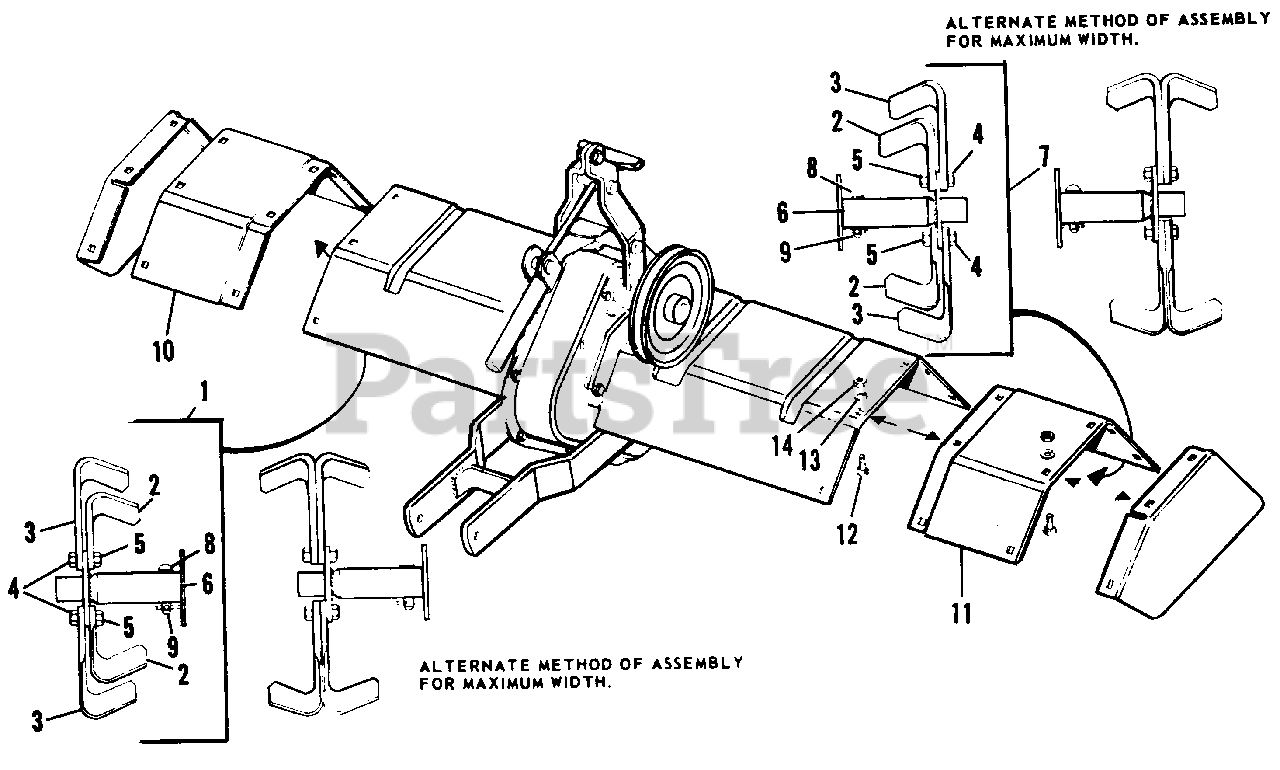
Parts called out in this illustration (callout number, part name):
1	Blade Assembly, L.H.
2	Blade, L.H. Tine
3	Blade, R.H. Tine
4	Hex. Capscrew, 7/16"-20 x 1-1/4"
5	Full Lock Nut,7/16"-20
6	Plate Assy. Tine Extension
7	Blade Assembly, R.H.
8	Tine Shaft Pin
9	Spring Clip
10	Deflector Extension, R.H.
11	Deflector Extension, L.H.
12	Carriage Bolt, 5/16"-18 x 1/2"
13	Lock Washer, 5/16"
14	Full Hex. Nut, 5/16"-18
